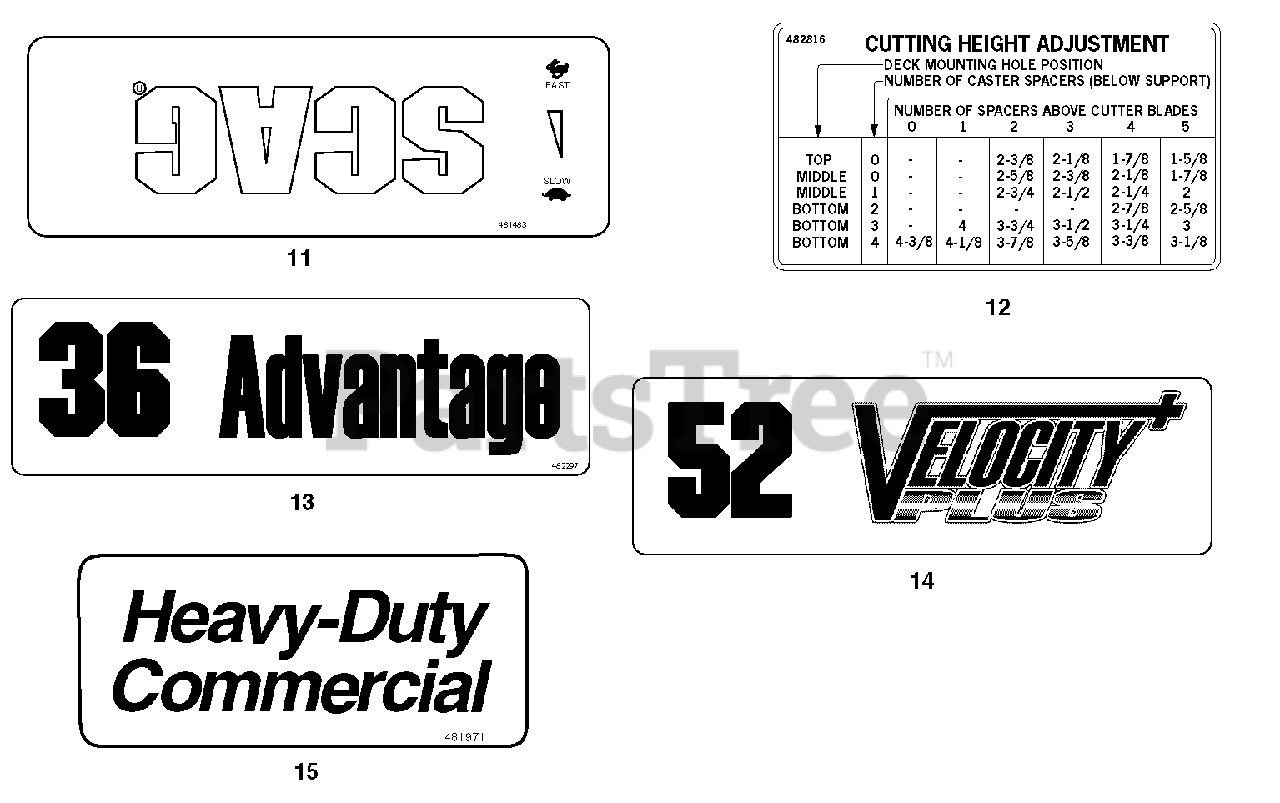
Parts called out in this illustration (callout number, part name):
11	Decal, Instrument Panel - Front
12	Decal, Height of Cut
13	Decal, 32
13	Decal, 36 Advantage
14	Decal, 48 Velocity Plus
14	Decal, 52 Velocity Plus
15	Decal, Heavy Duty Commercial
